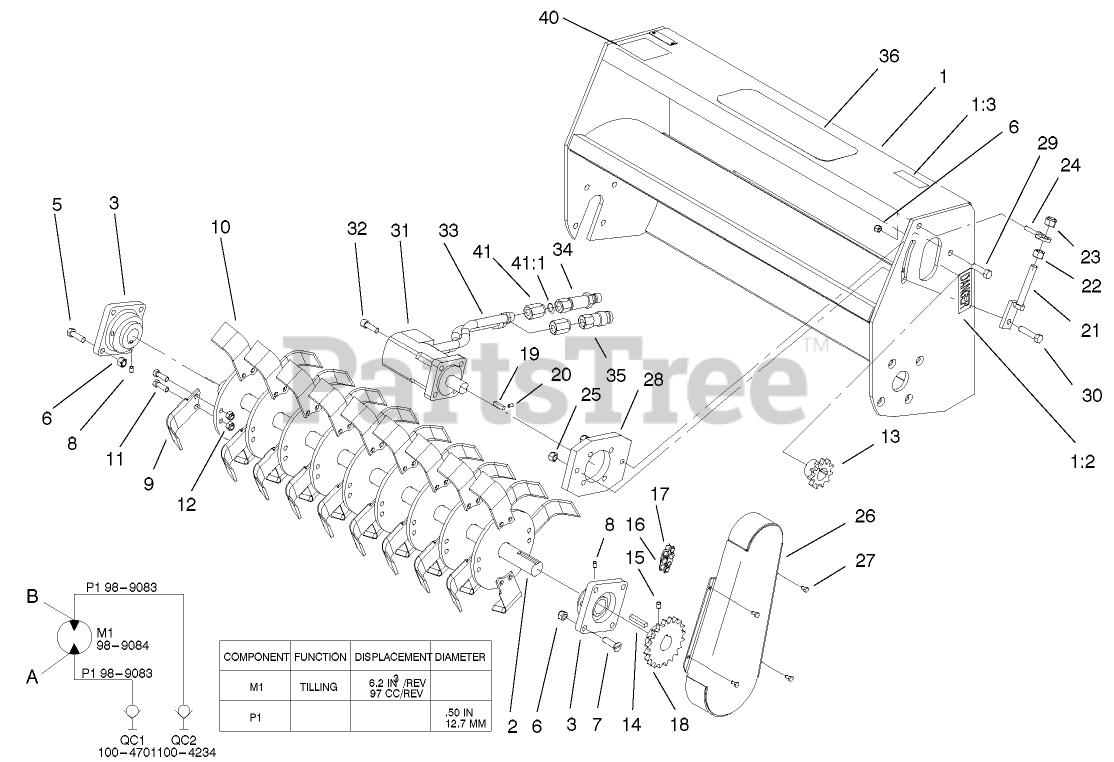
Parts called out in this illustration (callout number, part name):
1	TILLER FRAME ASM
1:2	DECAL-DANGER
1:3	DECAL-WARNING
2	SHAFT-TINE
3	BEARING ASM
5	SCREW-HH
6	NUT-LOCK, NI
8	SCREW-SET
9	TINE-RH
10	TINE-LH
11	SCREW-HH
12	NUT-LOCK, INSERT
13	SPROCKET-11 TOOTH
14	KEY-SQUARE
15	SCREW-SET
16	CHAIN-ROLLER
17	LINK-CONNECTING
18	SPROCKET-20 TOOTH
19	KEY-SQUARE
20	SCREW-SET
21	CHAIN ADJUSTMENT ASM
22	NUT-HEX
23	NUT-LOCK NI
24	HOLDER-ADJUSTMENT
25	NUT-LOCK, NI
26	COVER-CHAIN, TILLER
27	SCREW-HH
28	PLATE-MOUNT, MOTOR
29	SCREW-HH
30	SCREW-HH
31	MOTOR-HYD
32	SCREW-HSH
33	HOSE - HYDRAULIC
34	NIPPLE-CONNECT, PRESSURE
35	COUPLER-FACE, FLUSH
36	DECAL-DINGO, FRONT
40	DECAL
41	ADAPTER-HYD
41:1	O-RING
